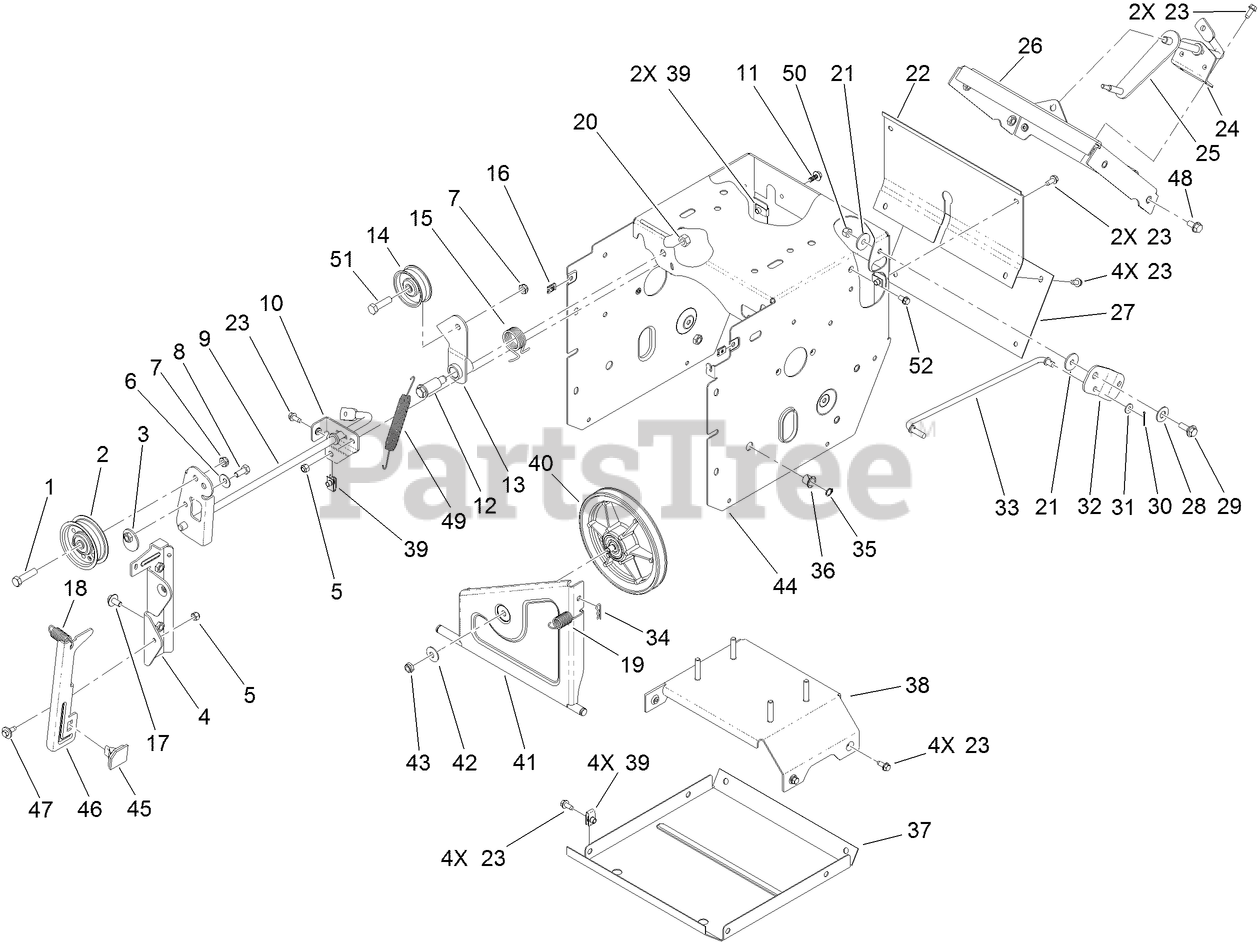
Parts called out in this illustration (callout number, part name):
1	SCREW-HH
2	PULLEY-IDLER
5	NUT-LOCK, NI
6	WASHER-BELLEVILLE
8	SCREW-HH
9	IMPELLER CLUTCH ASM
10	BRACKET-CLUTCH, IMPELLER
11	SCREW-HHF
12	BOLT-SHOULDER
13	ARM-IDLER, TRACTION
14	PULLEY-IDLER
15	SPRING-TORSION
16	NUT-SPEED
17	SCREW-HHF
18	SPRING-EXTENSION
19	SPRING-EXTENSION
20	NUT-LOCK, NI
21	WASHER-PIVOT
22	COVER-UPPER
23	SCREW-HWH
24	BRACKET-ROD, SHIFT
25	LEVER-CONTROL, TRACTION
26	SHIFT PLATE ASM
27	COVER-LOWER
28	WASHER
29	SCREW-SHOULDER
30	PIN-COTTER
31	WASHER-PLAIN
32	BELLCRANK-DRIVE
33	LINK-CONTROL, SPEED
35	RING-RETAINING
36	BUSHING-NYLINER
37	PAN-BOTTOM
38	FRAME BRACE ASM
40	PULLEY-TRACTION
41	BRACKET-WHEEL, FRICTION
42	WASHER-BELLEVILLE
43	NUT-HEX
44	FRAME-TRACTION
45	PAD-BRAKE
47	SCREW-SHOULDER
48	SCREW-HWHTF
50	NUT-LOCK, NI
51	SCREW-HH
52	SCREW-HWH
